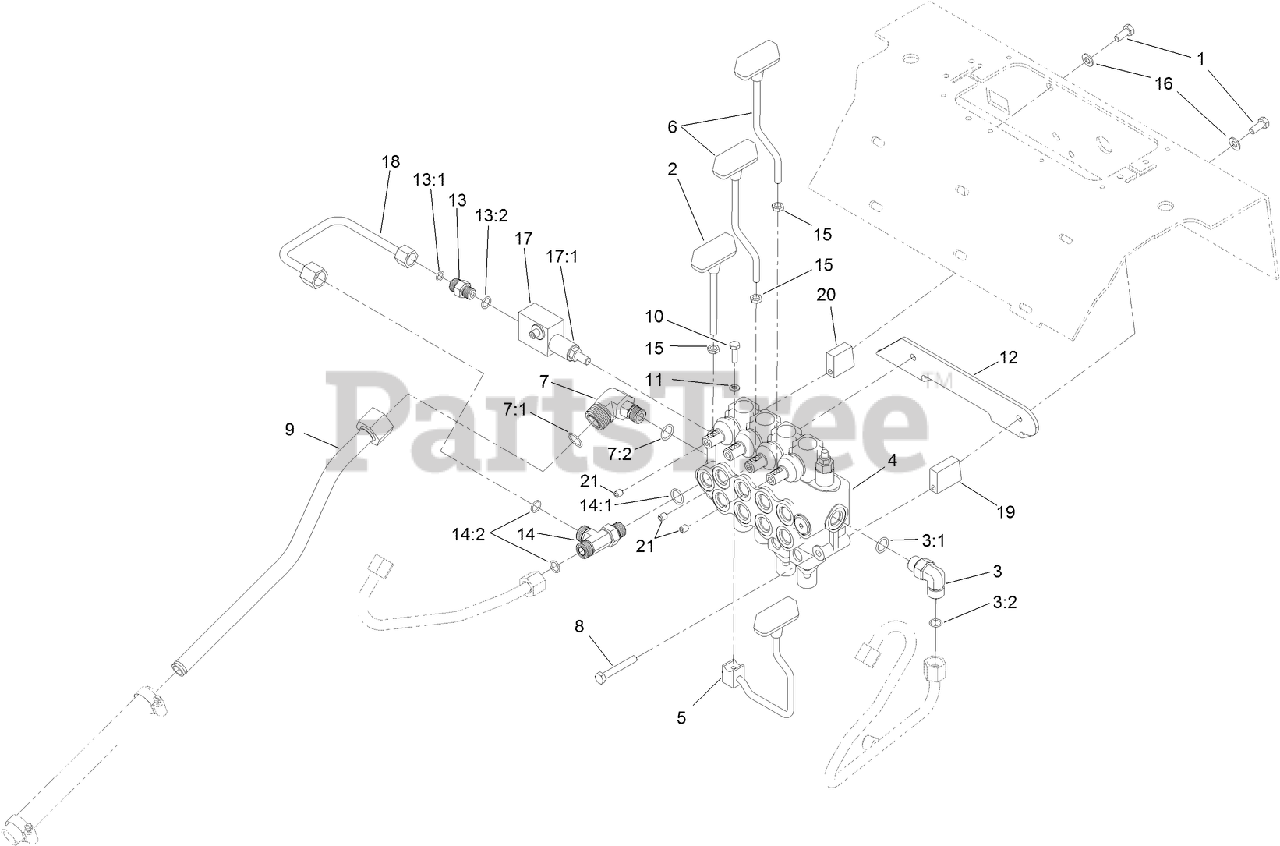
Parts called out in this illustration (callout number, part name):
1	SCREW-HH
2	LEVER-CYLINDER
3	FITTING-ELBOW, 90 DEG
3:1	O-RING
3:2	O-RING
4	HYD FOUR SPOOL VALVE ASM
5	LEVER-CONTROL
6	LEVER-DRIVE
7	FITTING-ELBOW, 90 DEG
7:1	O-RING
7:2	O-RING
8	SCREW-HH
9	TUBE-TANK, HYD
10	SCREW-HH
11	WASHER-LOCK
12	BRACKET-COVER, MOUNT
13	FITTING-STRAIGHT
13:1	O-RING
13:2	O-RING
14	FITTING-TEE
14:1	O-RING
14:2	O-RING
16	WASHER-PLAIN
17	RELIEF VALVE ASM
17:1	CARTRIDGE-VALVE, RELIEF
18	LINE-HYD
19	SPACER-LOWER V
20	SPACER-UPPER V
21	SCREW-SET, HSH
